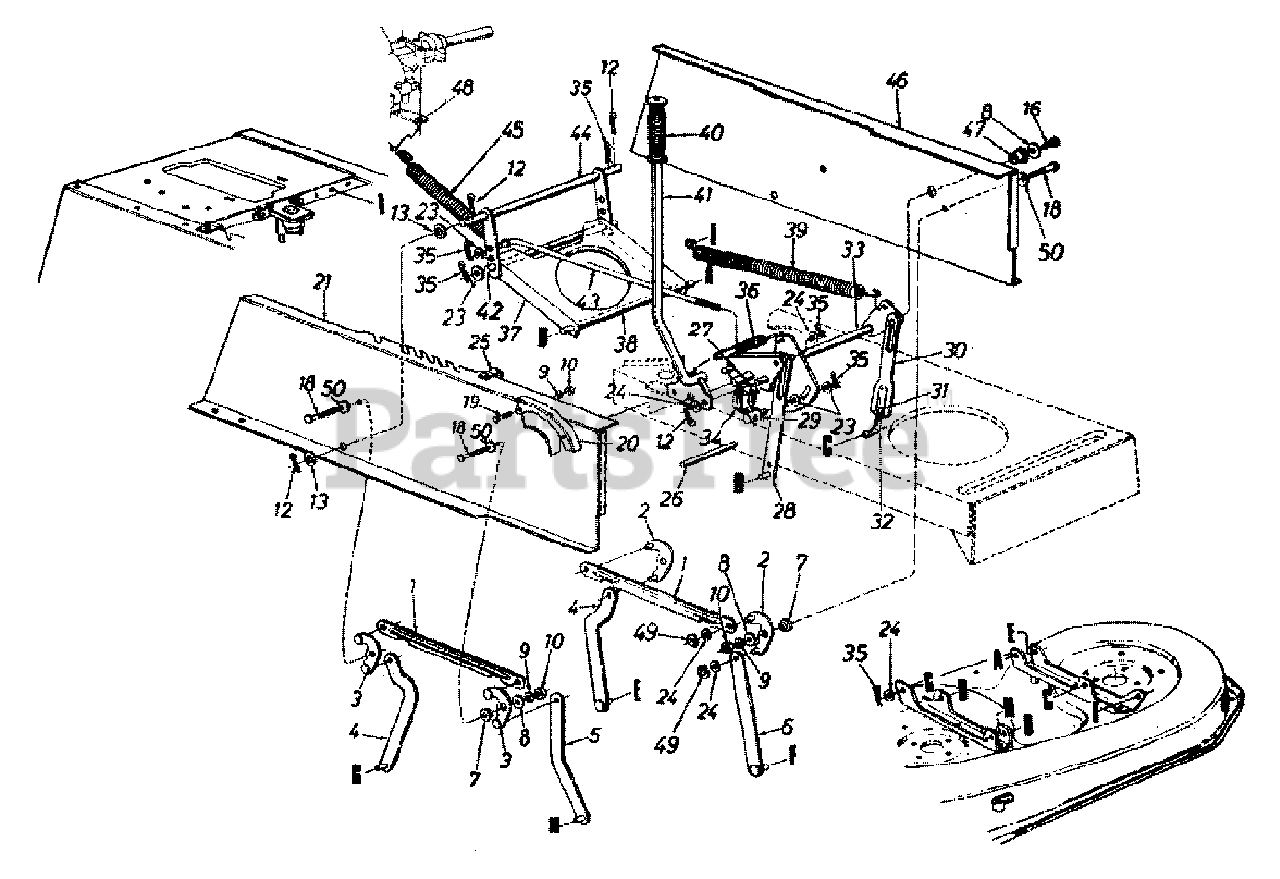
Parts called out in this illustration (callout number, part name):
3	Pivot Link Ass'y.-R.H.
7	Shld. Spacer .318" I.D.
8	Fl-Wash. .344" I.D. x .62" O.D.
9	L-Wash. 5/16" I.D.
10	Hex Nut 5/16-18 Thd. (Gr. 5)
12	Cotter Pin 1/8" Dia.
13	Fl-Wash. .635" I.D. x 1.0" O.D.
16	Hex Wash. TT-Tap Scr. 5/16-18 x .75" Lg.
18	Hex Wash. Hd. Scr. 5/16-18 x .875" Lg.
19	Hex Bolt 5/16-18 x .75" Lg.
24	Fl-Wash. .531" I.D. x .93" O.D.
26	Running Board Rod
27	Hex Wash. Hd. Tap Scr.
31	Hex Nut 1/2-20 Thd. (Gr. 5)
32	Lift Link Adjuster
33	Lift Shaft Ass'y.
34	Safety Switch (Deck)
35	Inter. Cotter Pin 3/8" Dia.
36	Extension Spring
39	Extension Spring
40	Grip (Lift Handle)
43	Disengagement Rod
49	"E"-Ring
50	Bell-Wash. .325" I.D.
97675A-0637	LIFT HANDLE ASSY POWDER BLACK - POWDER BLACK (0637)
97675A-0638	LIFT HANDLE ASSY POWDER BLACK - MTD/TROY-BILT RED (0638)
97675A-0648	LIFT HANDLE ASSY POWDER BLACK - TECH GRAY (0648)
97675A-0665	LIFT HANDLE ASSY POWDER BLACK - YARDMAN GREEN (0665)
